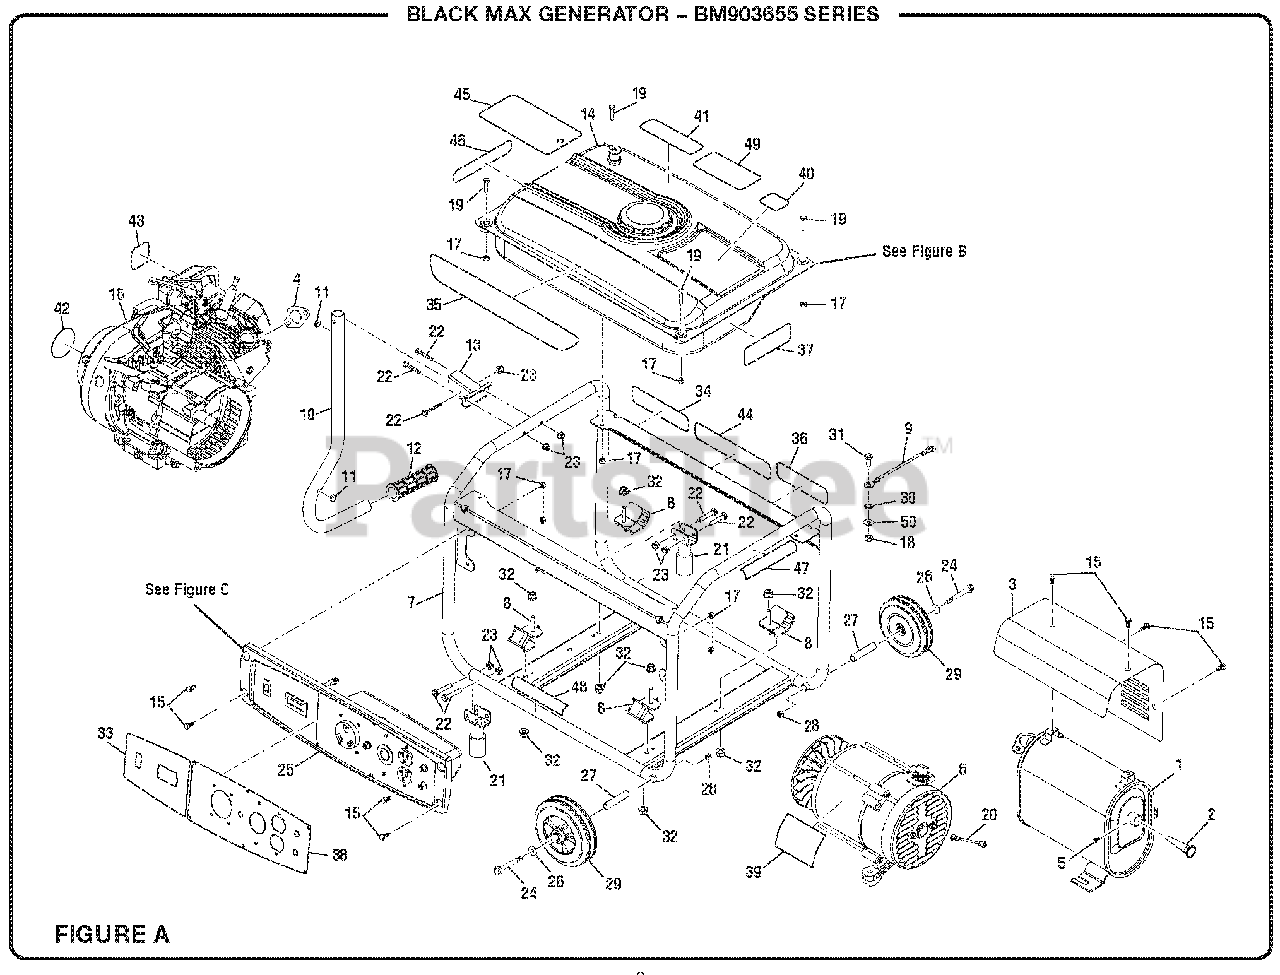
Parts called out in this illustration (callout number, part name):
2	Spark Screen
3	Heat Shield
4	Exhaust Gasket
5	Set Screw (Spark Arrestor)
6	Generator Head Assembly
7	Carrier Assembly
8	Isolators (45deg)
9	Ground Wire Assembly
10	Handle Assembly (Inc. Key Nos. 11-13)
11	Handle Bumper
12	Handle Grip
13	Handle Bracket
14	Fuel Tank Assembly
15	Screw (M6 x 14 mm)
16	Engine (Ducar 208cc)
17	Lock Nut (M6)
18	Lock Nut (5/16-18)
19	Bolt (M6 x 20 mm, Hex Hd.)
20	Bonding Wire
21	Foot Assembly
22	Bolt (1/4-20 x 1.5 in.)
23	Lock Nut (1/4-20)
24	Bolt (3/8-16 x 4.25 in.)
25	Panel Assembly
26	Washer (3/8 in.)
28	Lock Nut (3/8-16)
29	Wheel (7 in.)
30	Star Washer (5/16 in.)
31	Bolt (5/16-18 x 19 mm)
32	Flange Nut (M8)
33	Control Panel Label (Left)
34	Black Max Label
35	Logo Label
36	Hot Surface Label
37	Combustion Label (Eng/Sp)
38	Control Panel Label (Right)
39	Data Label
40	E85 Label
41	CPSC Label
42	Recoil Housing Label
43	Choke Label
44	Ground Warning Label
45	Danger Hang Tag
46	Engine Start Label
47	Fire Danger Label
48	Lubricant Label
49	Warning Label
50	Lock Washer (5/16 in.)
